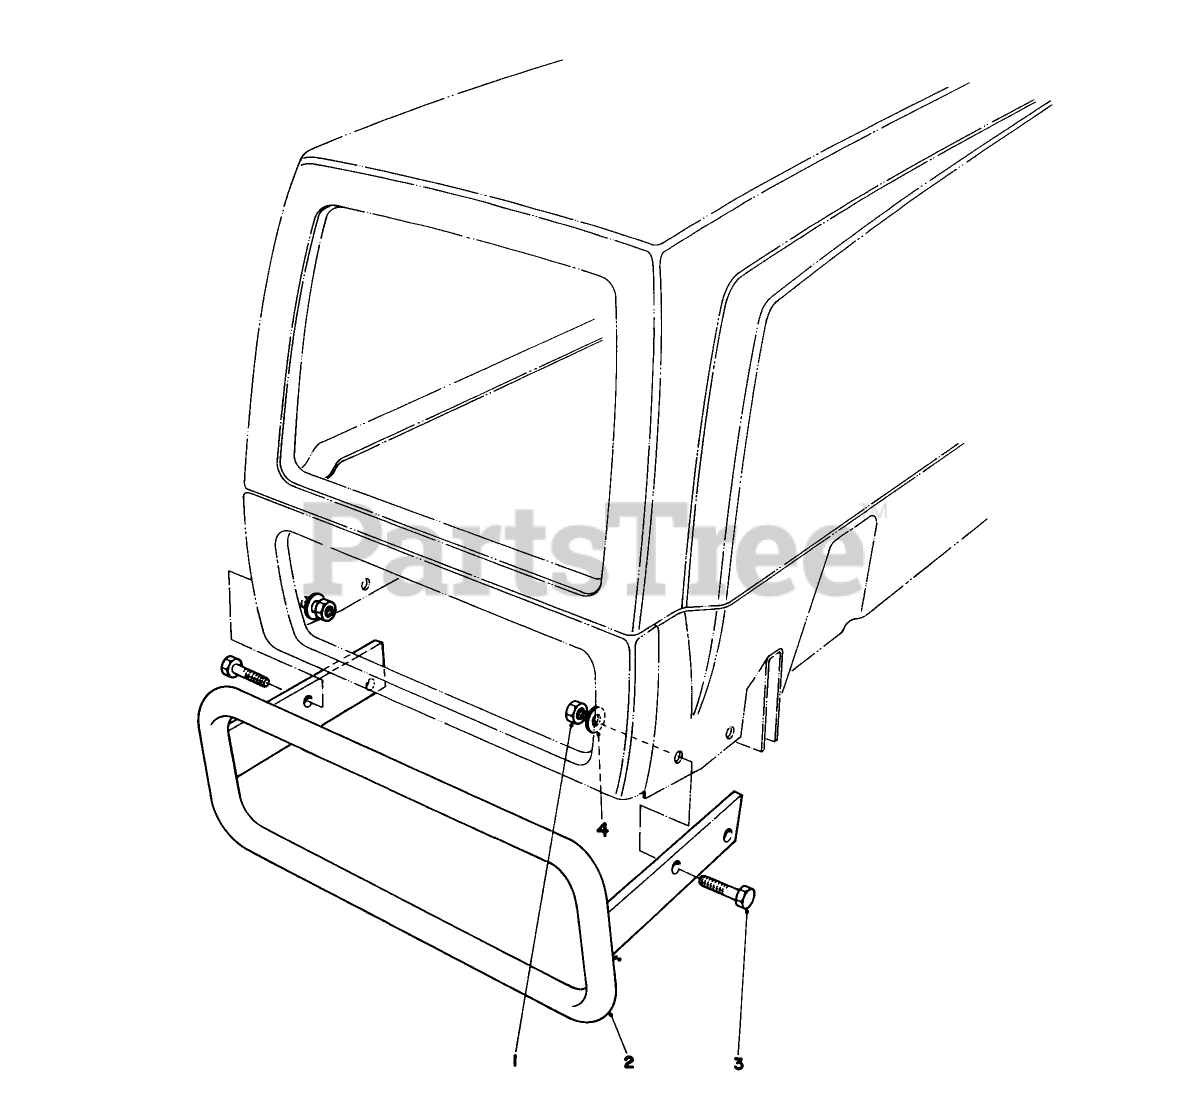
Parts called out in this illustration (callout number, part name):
1	NUT-LOCK, CONE
2	Bumper
3	SCREW-HH
4	WASHER-PLAIN
